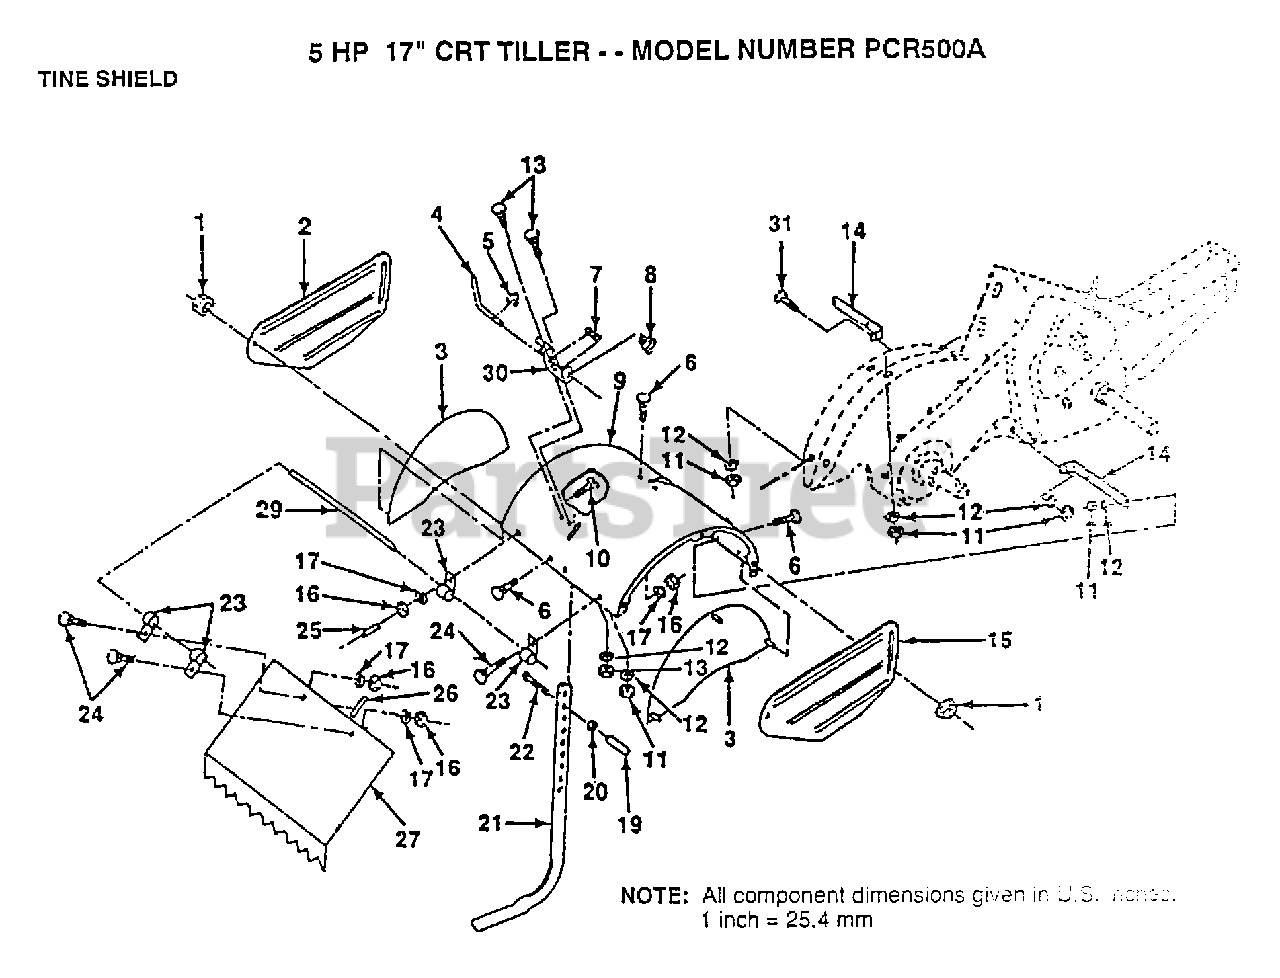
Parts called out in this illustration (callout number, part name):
1	NUT
2	SHIELD.SD.OUT.LH
3	SHIELD SIDE
4	STAKE PIN TI
5	KLIP RING TI
6	BOLT
7	SPRING TI
8	SPRING CRT
9	SHIELD TINE
10	BOLT
11	NUT.HEX.5/16-18
12	LOCKWASHER
13	BOLT CRT
14	BRKT SHIELD TINE
17	LOCKWASHER
19	GRIP CRT
20	NUT.HEX.3/8-16UNC
22	BOLT
23	HINGE CRT
24	BOLT
25	VINYL CAP TI
26	PAD IDLER TI
27	"SHIELD,LEVEL"
29	PIN HINGE
30	LATCH BRACKET TI
31	BOLT
